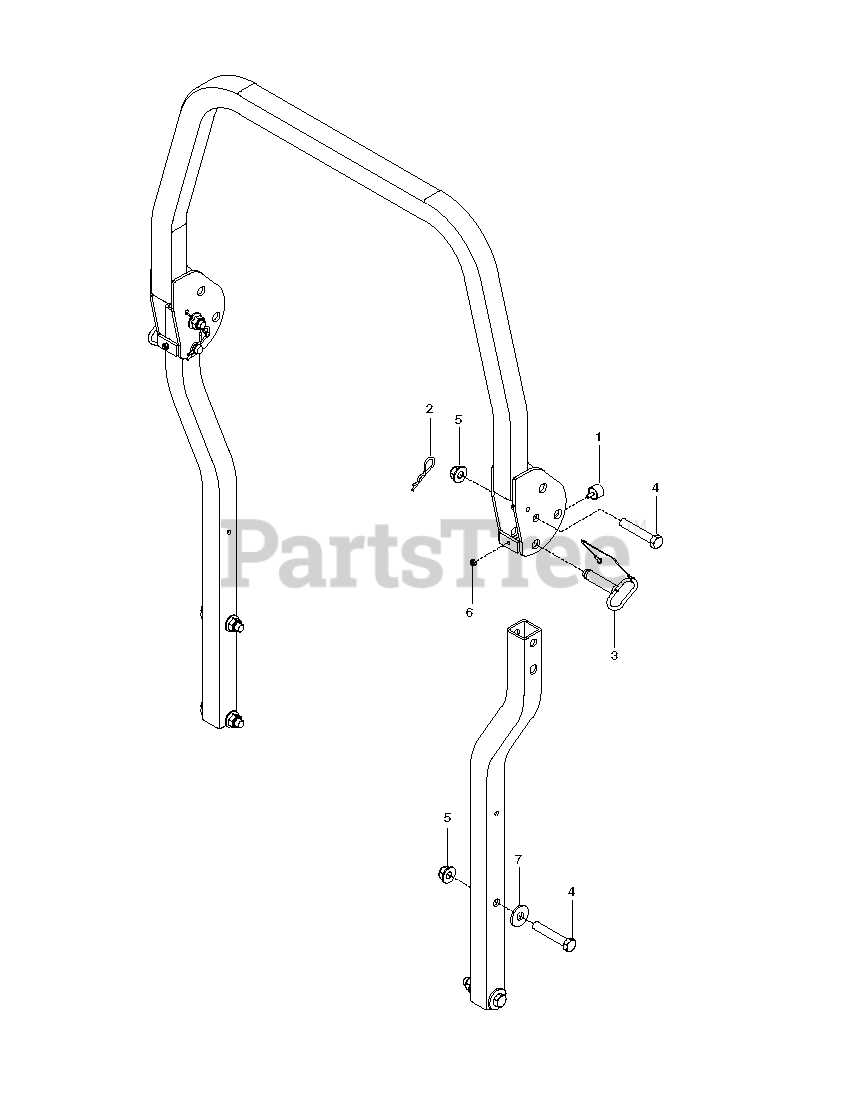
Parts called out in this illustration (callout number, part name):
1	BUMPER, MALE STUD, 1/4-20
2	PIN HAIR .148 X 2-15/16 #210
3	PIN, ROPS
4	5/8-11 X 3-1/2 HHB GRADE 5
5	NUT 5/8-11 FLG NYLOC ZD
6	RP_NUT 1/4-20 NYLOC
7	WASHER, 5/8 FLAT
